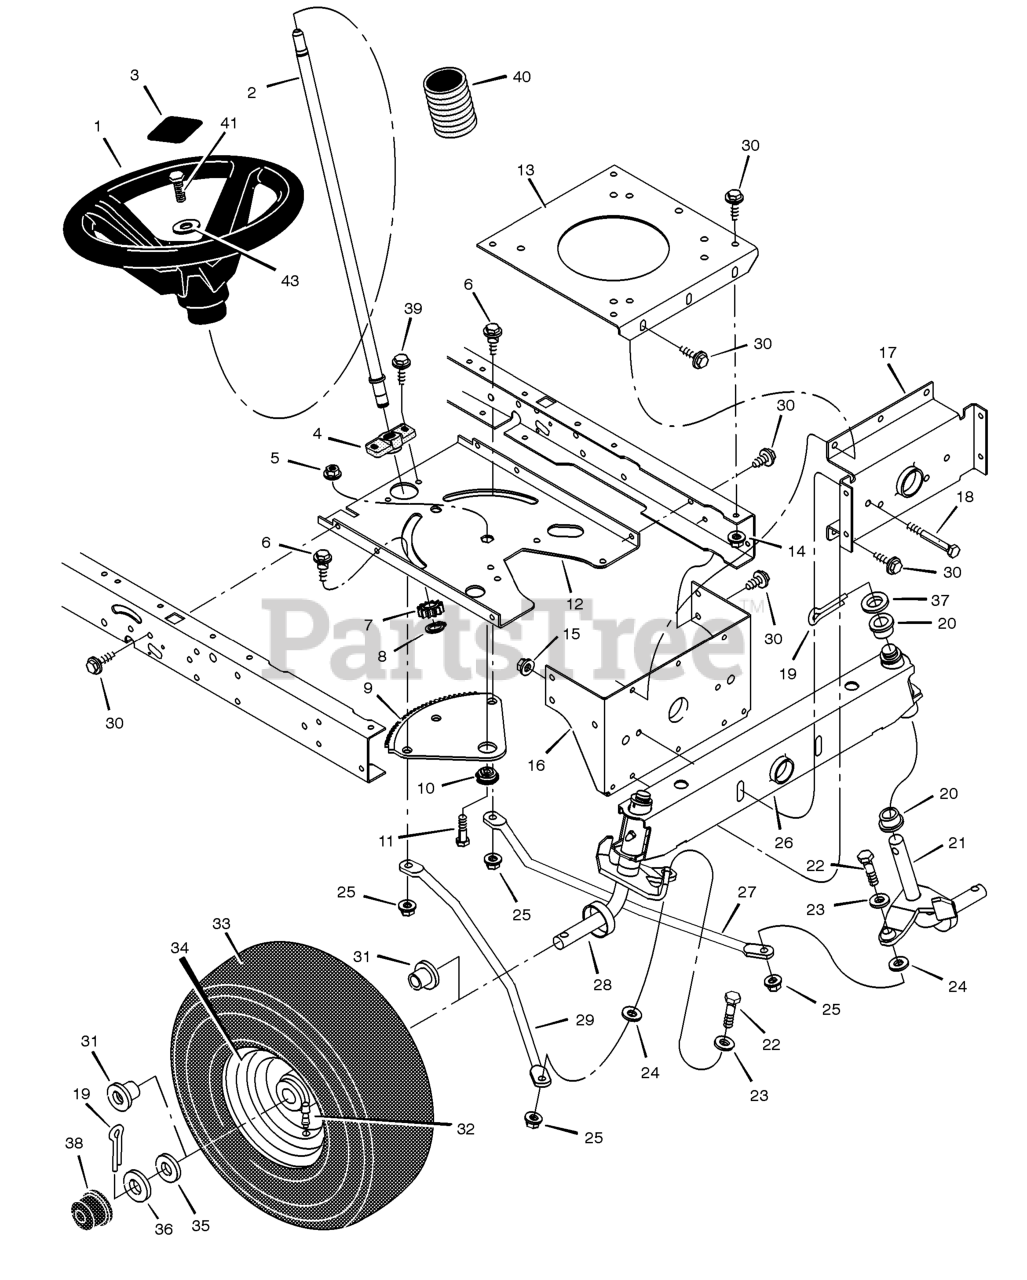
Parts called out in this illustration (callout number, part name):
1	Wheel, Steering
2	Post, Steering
3	Insert, Steering Wheel
4	Bearing
5	Nut, Flange
6	Bolt, Shoulder
7	Gear, Pinion
8	Ring, Snap
9	Gear, Sector
10	Bearing
11	CAPSCREW, Hex Head, 5/16-18 x 1
12	Plate, Steering
13	Plate, Engine
14	Nut, Flange
15	Nut, Flange
16	Bracket, Hanger
17	Axle, Hanger
19	Pin, Cotter
20	Bearing
21	Spindle Assembly, Left
22	Bolt
23	Washer
25	Nut, Flange
26	Axle Assembly
27	Drag Link, Left
28	Spindle Assembly, Right
29	Drag Link, Right
31	Bearing, Wheel
32	Stem, Valve
33	Tire *
34	Wheel and Tire Assembly
38	Hub Cap
40	Bellows
41	Screw, Hex
43	Washer
